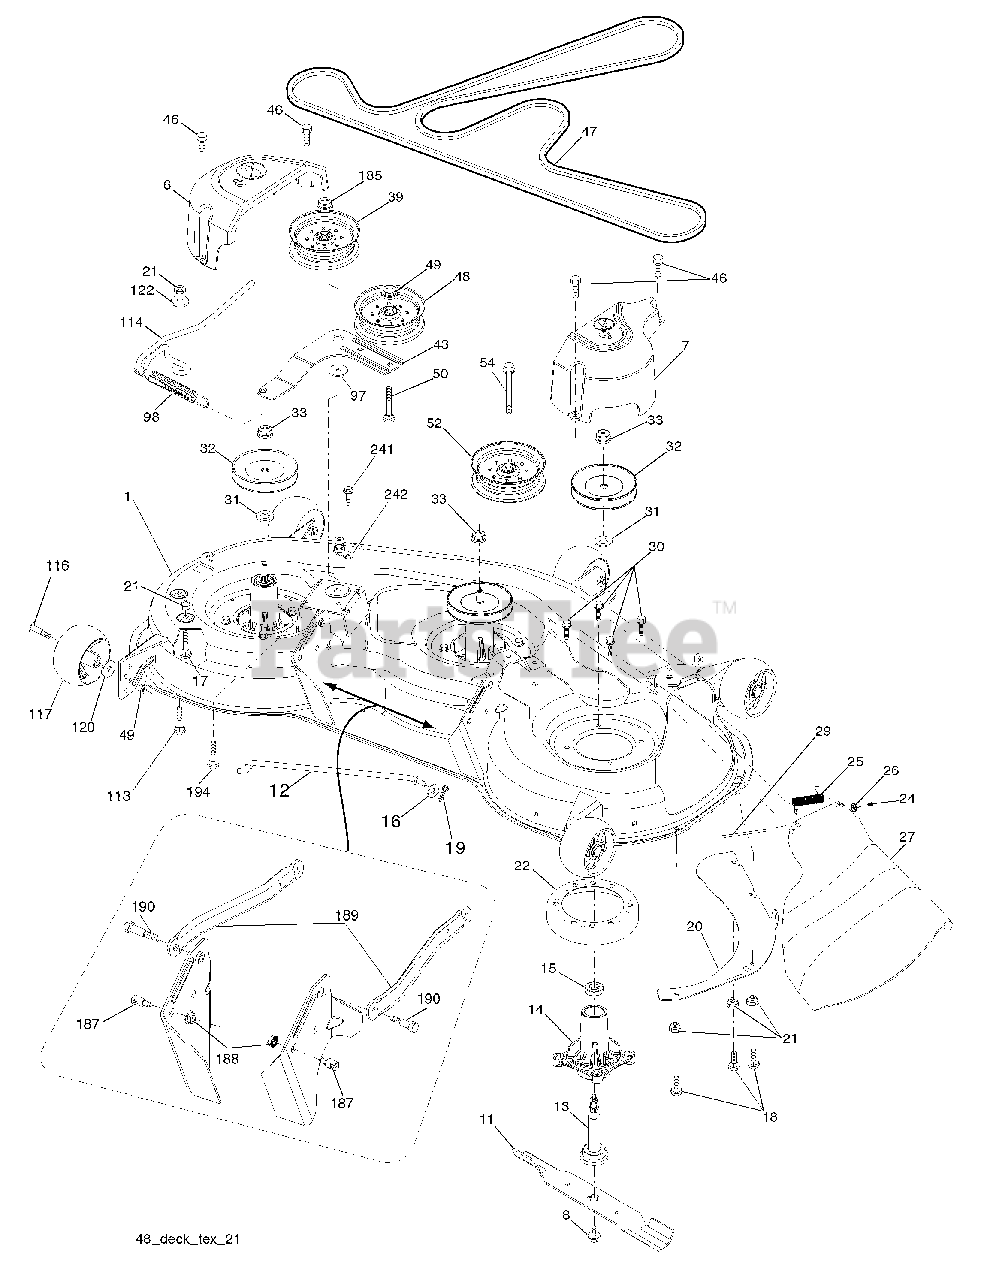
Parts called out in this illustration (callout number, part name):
1	Deck Weldment Mower
6	Cover Mandrel LH
7	Cover Mandrel RH
8	Bolt 7/16 Asm. Blade
11	Blade High Lift
11	Blade Mulching
12	Rod Anti Sway
13	Shaft Asm. w/Lower Bearing
14	Housing, Mandrel
15	Bearing, Ball, Mandrel
16	Washer 13/32 x 13/16 x 12 Ga.
17	Bolt Carr 5/16-18 x 5/8
18	Bolt RdHd 5/16-18 unc x 5/8
19	Pin Cotter 5/16 Bow Tie Lock
20	Baffle, Vortex
21	Nut, Crownlock 5/16-18 unc
24	Cap Sleeve
25	Spring, Torsion
27	Deflector Shield
29	Rod, Hinge
30	Screw, Thdroll Washer Head
31	Washer, Spacer Mower Vented
32	Pulley, Mandrel
33	Nut, Flg. Top Lock
39	Pulley, Idler, 4.50 HUB
43	Arm, Idler
46	Screw, Thdroll. 1/4-20 x 5/8
47	Belt Deck Drive
48	Pulley, Idler Primary
49	Nut, Lock Flg. 3/8-16 unc
50	Bolt Carr. 3/8-16 x 1-1/2 Gr. 5
52	Pulley Idler 4.50 RAW
54	Screw 3/8-16 x 2-1/4
97	Washer Hardened
98	Spring Drive
113	Bolt Rdhd Sqnk 5/16-18 x 3/4
114	Rod Tension Relief
116	Bolt, Shoulder
117	Gauge Wheel
120	Washer 13/32 x 1-1/4 x 12 Ga.
122	Bushing Tension Relief
185	Nut Lock Flange 7/16-14 Gr. 5
187	Stud Fastener w/"D" Anti-Rotation
188	Nut Lock Hex Flange
189	Arm Susp. Mower Rear
190	Bolt Shoulder
194	Bolt Carr Sqnk 7/16-24 x 2
241	Screw TT #10-32.5. 3/8 Flange
242	Port Washout
242	Mandrel Assembly
242	Coupling Quick Connect
242	Replacement Mower, Complete
